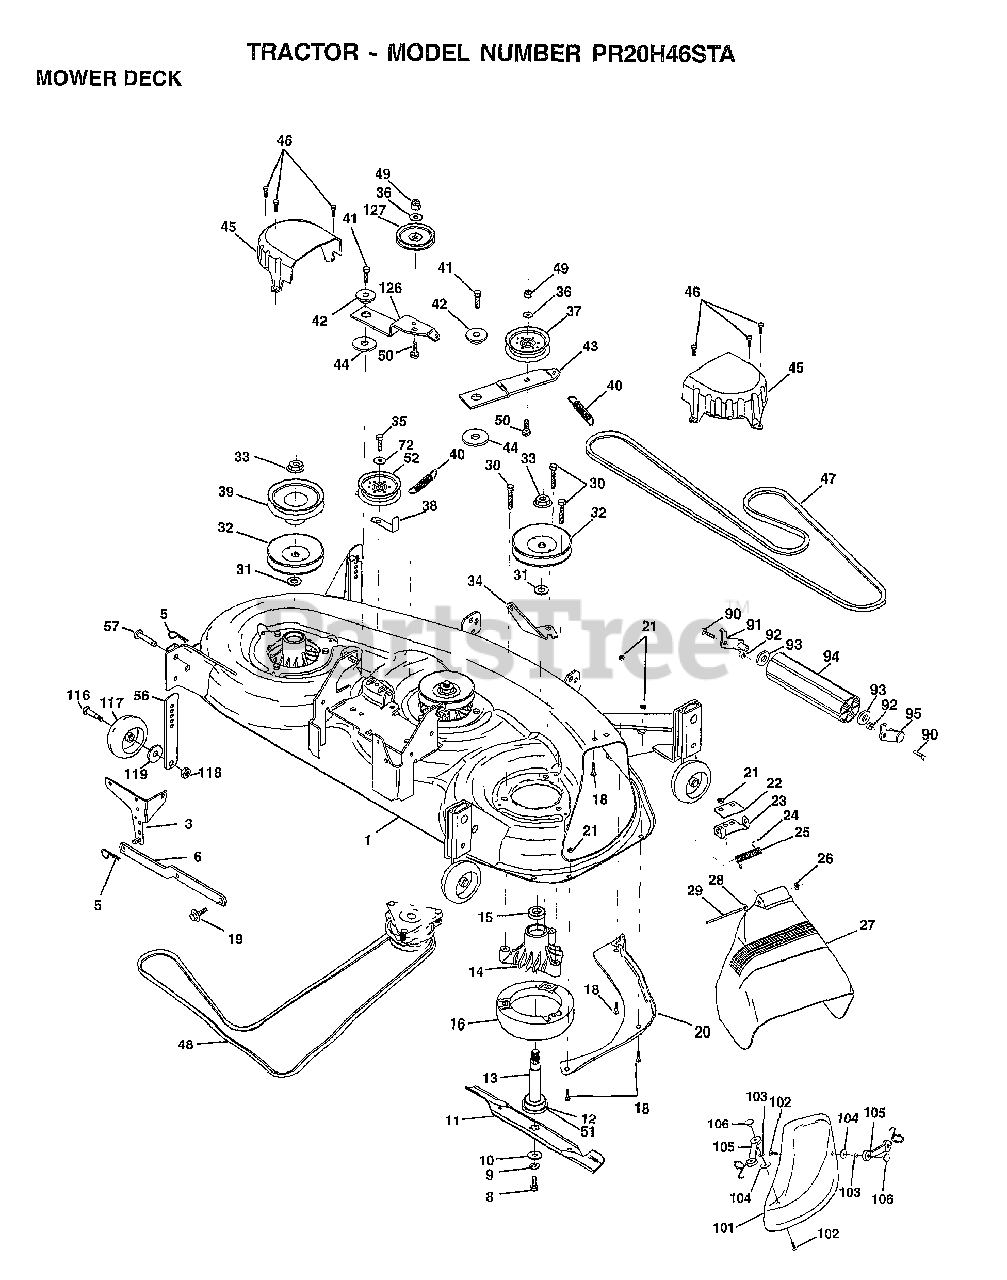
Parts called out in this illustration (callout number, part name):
3	BRKT.ASM.SW.44/50
8	BLADE BOLT
10	WASHER.HARD.BLADE
11	BLADE
12	BEARING.BALL
13	SHAFT.ASM.W/BRNG
14	HOUSING.MAND.44.V
15	BEARING
16	STRIPPER RND MWR
18	BOLT
19	BOLT SHD 5/16-18
20	BAFFFLE.VORTEX.46
22	STIFFENER BRACKET
23	BRACKET DEFLBRACKET DEFLECTOR MOWER 42''
24	CAP-SLEEVE LT
26	NUT PUSH M
27	SHIELD
28	WASHER
29	HINGE ROD
30	"SCREW-THD ROLL,WA"
31	WASHER
32	PULLEY
35	SCREW LT
36	WASHER
37	PULLEY
38	KEEPER
39	PULLEY
40	"SPRING.SEC.44""VEN"
41	SCREW
42	SPACER RETAINER
44	HARDENED WASHER
45	COVER.MANDREL.46
46	SCREW.1/4-20X5/8
47	BELT-V.SEC.46.KEL
48	BELT.MWR.PRM.85.4
50	BOLT.3/8-16X1.50
51	WASHER.FELT.
52	PULLEY
57	RIVET-PAN HEAD
72	WASHER HYT
90	BOLT
92	NUT
93	WASHER
101	COVER.MULCHING.
102	SCREW
103	LOCKWASHER
104	WASHER #10
105	LATCH ASSY.BAGGER
106	WELDNUT
116	BOLT.SHOULDER
117	WHEEL GAGE DONUT
118	LOCKNUT
119	WASHER
127	PULLEY
